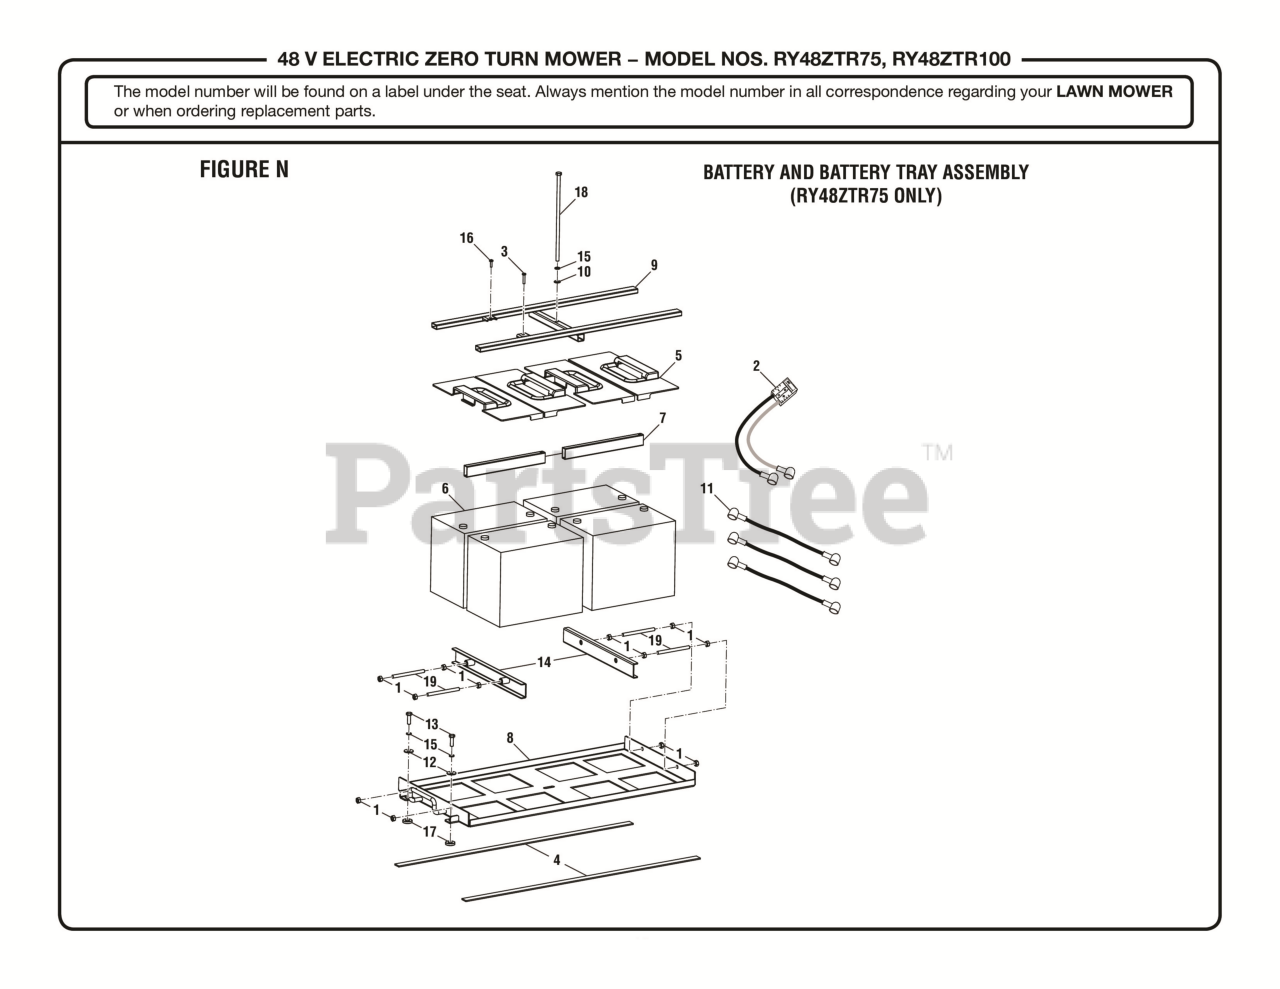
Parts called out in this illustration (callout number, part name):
1	Hex Nut (M8)
2	Battery Cable 2, ZTR
3	Screw (M5 x 25 mm)
4	Battery Tray Slider
5	Battery Shield, ZTR
6	Battery (LPC12-75, RY48110, RY48112)
7	Battery Spacer (LPC12-75)
8	Battery Tray
9	Battery Tie Down
10	Washer (OD16 x ID8.4 x 1.6t)
11	Battery Cable w/Covers (Red and Black, 120 mm)
12	Washer (OD 24 x ID8.4 x 2t)
13	Bolt (M8 x 25 mm, Hex Hd.)
14	Battery Holder Bracket
15	Lock Washer (OD9.8 x ID8.5 x 5t)
16	SCREW,PPHMS, M5 X 0.8 X 16 - STEEL,
17	Metal Bushing
18	Hex Bolt (M8 x 240 mm)
19	Threaded Rod (M8 x 100 mm)
